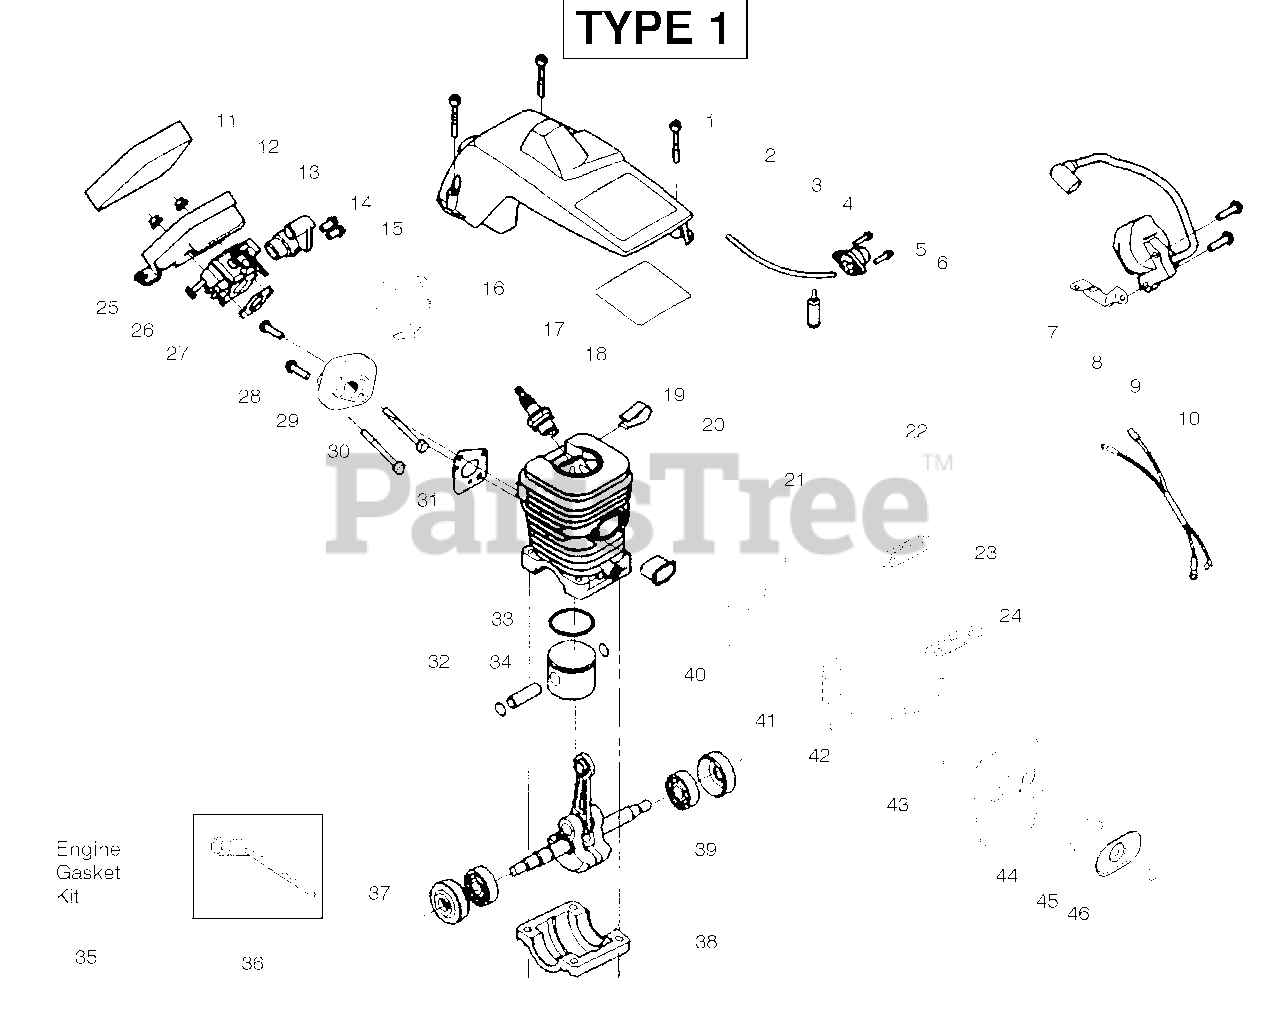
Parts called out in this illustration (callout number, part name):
2	Assy-Cylinder Shield
3	Kit-Fuel Line (Small)
4	Assy- Air Purge
6	Assy-Fuel Pick-up
7	Strap-Ground
8	Ignition Module
10	Assy-Wire Harness
11	Foam- Air Filter
13	Grommet-Carb Adjust
14	Limiter Cap-High
15	Limiter Cap-Low
16	Seal-Carb Adapter
17	Reflector-Heat
18	Spark Plug (RCJ-7Y)
19	Clip-High Tension Lead
20	Kit-Cylinder
21	Insulator-Heat
22	Screw-Outlet cover
23	Cover - Outlet
24	Kit-Spark Arrestor
25	Air Filter Housing
26	Kit-Carburetor (WT600)
27	Gasket-Carb.
29	Carb. Adapter
31	Gasket-Carb Adaptor
32	Kit-Piston
33	Ring-Piston
34	Retainer-Piston Pin
35	Kit-Engine Gasket
36	Bar Wrench
37	Assy-Seal & Bearing
38	Cap-Crankcase
39	Assy-Crankshaft
40	Backplate
41	Guide-Outlet
42	Gasket-Muffler
43	Assy-Muffler
44	Bolt-Muffler
45	Cover-Bolt
46	Nut-Brass
